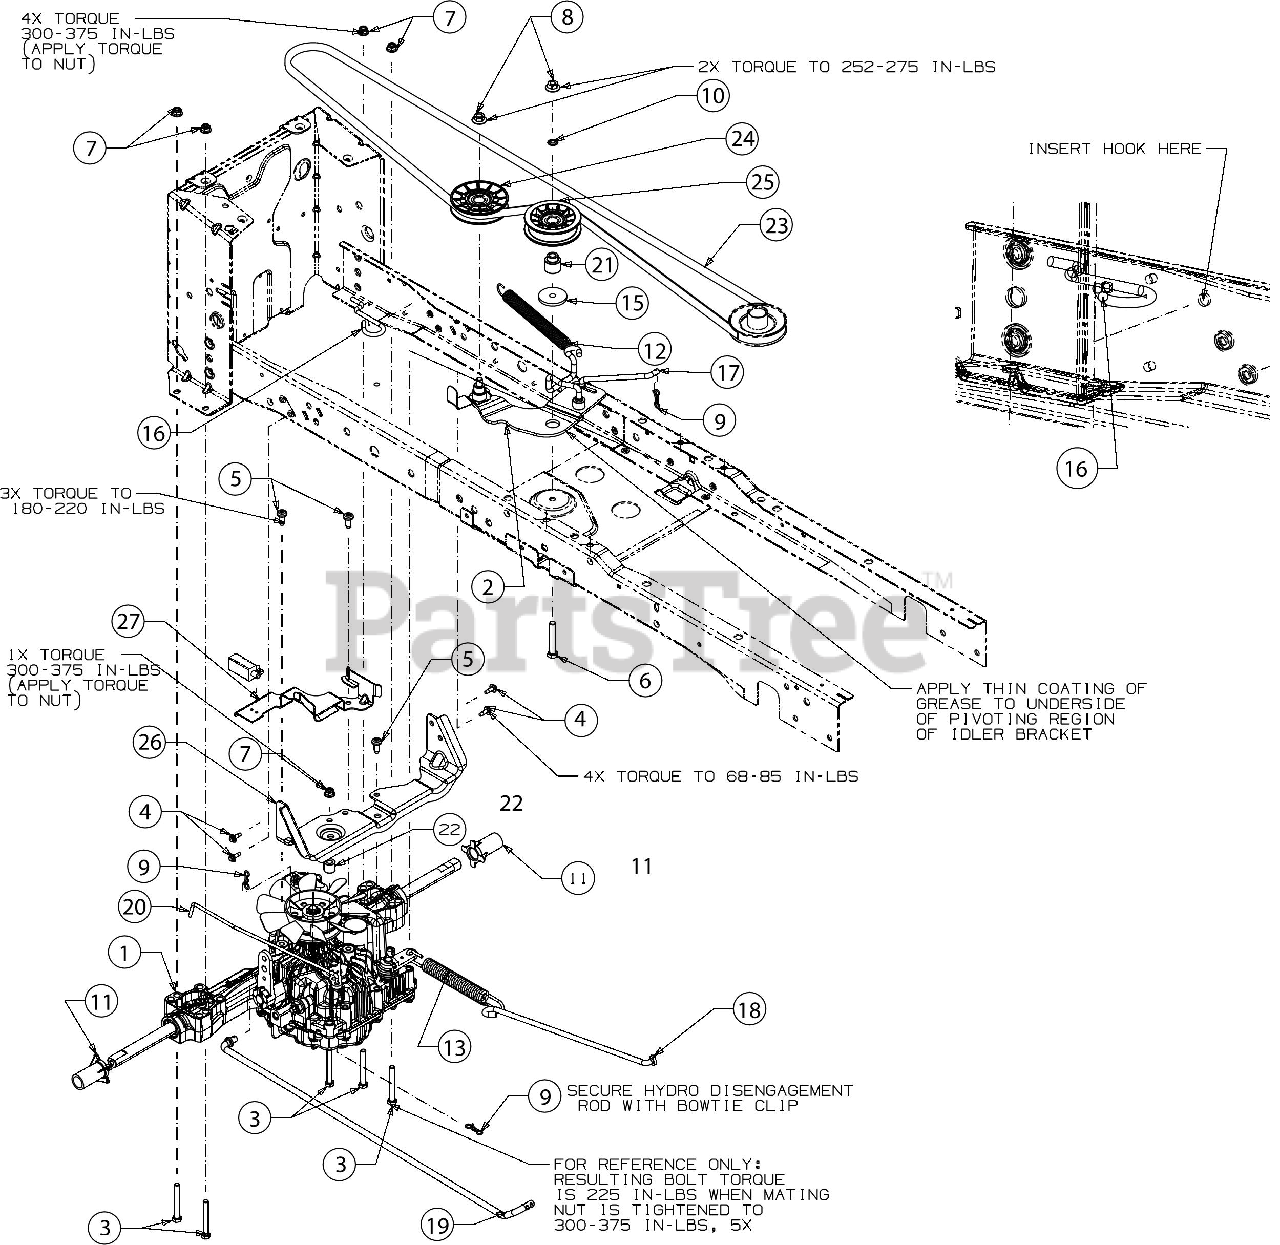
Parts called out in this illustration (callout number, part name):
1	TRANSMISSION ASSEMBLY
2	IDLER BRACKET ASSEMBLY
3	SCREW 5/16-18 x 2.5 GR 5
4	SCREW M6-1 x .625
5	SCREW 5/16-18 x .750
6	SCREW 3/8-16 x 2.25 GR5
7	FLANGE LOCK NUT 5/16-18
8	FLANGE LOCK NUT
9	BOW TIE COTTER PIN 1/4-5/16
11	AXLE SLEEVE .765 ID x 2.11 LG
12	EXTENSION SPRING .790 DIA x 8.41
13	EXTENSION SPRING 0.90 DIA x 8.14
14	GREASE-#251 EP (NOT SERVICEABLE)
15	SHOULDER SPACER
16	DECK SPRING HOOK
17	IDLER BRACKET LINK ROD
18	BRAKE ROD
19	HYDRO CONTROL ROD
20	HYDRO DISENGAGEMENT ROD
21	SHOULDER SPACER
22	SPACER .34 x .75 x .63 LG
23	V-BELT A SEC x 91.10
24	V-IDLER PULLEY 3.56 OD
25	FLAT IDLER PULLEY 3.00 OD
26	TRANSMISSON MOUNTING BRACKET
27	BELT KEEPER BRACKET
